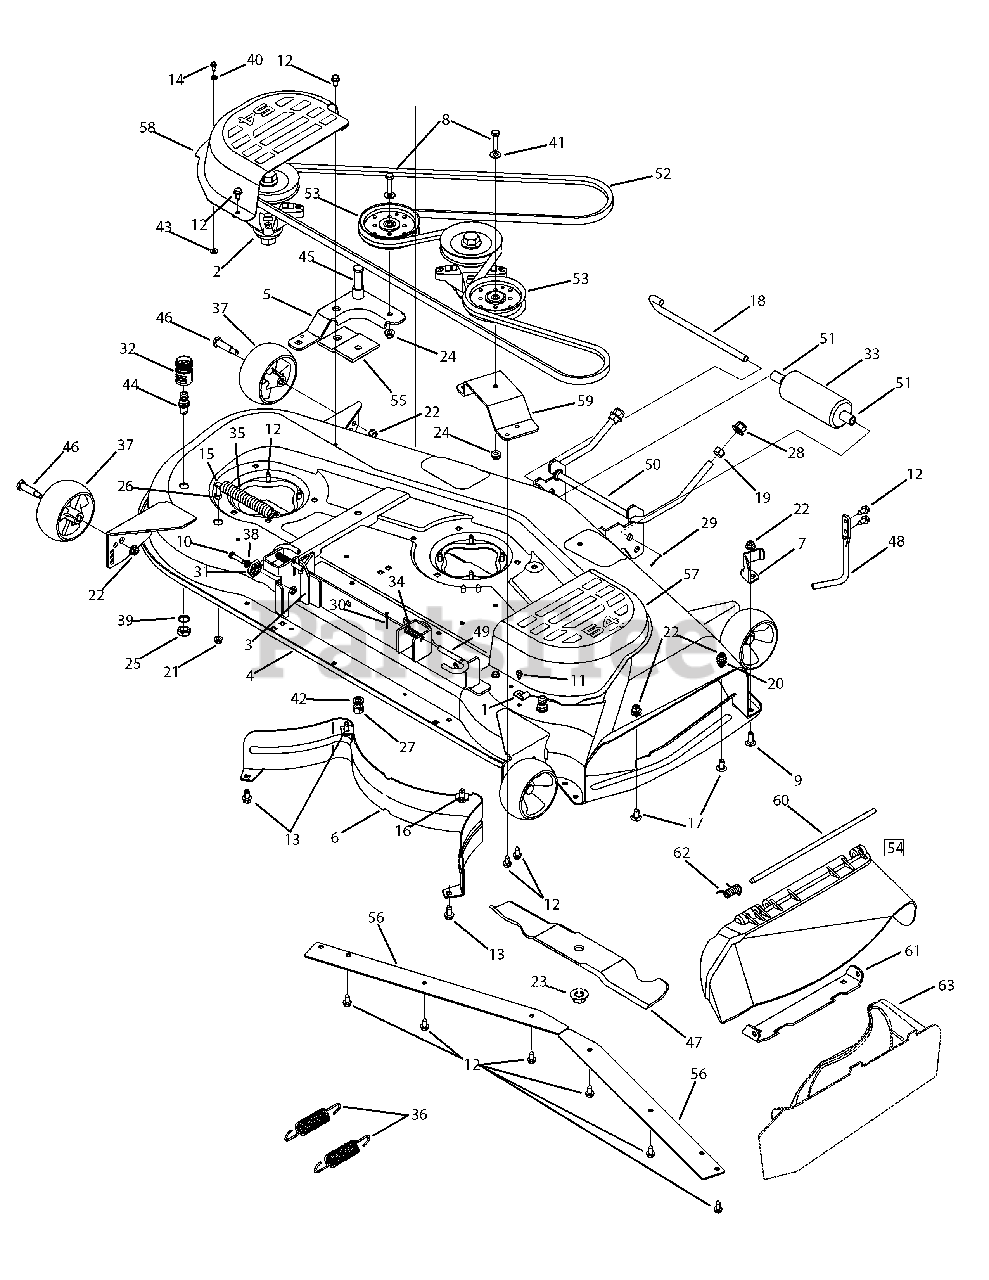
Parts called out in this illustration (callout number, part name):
1	Hook, Retainer Bracket
2	Spindle Assembly
8	Screw, 3/8-16 x 1.75
9	Screw, 3/8-16 x 1.0
10	Screw, 5/16-18 x 1.25
11	Screw, 1/4-20 x.500
12	Screw, 5/16-18 x.500
13	Screw, 3/8-16 x.750
14	Screw, 5/16-18 x.875
15	Screw, 5/16-18 x 2.00
16	Bolt, Carriage, 3/8-16 x 1.00
17	Bolt, Carriage, 3/8-16 x.750
18	Pin, Roller,.5" Dia. x 10.06
19	Nut, Hex, 1/2-13
20	Push Nut, 3/8
21	Nut, Flange Lock, 5/16-18
22	Nut, Flange Lock, 3/8-16
23	Nut, Flange, 5/8-18
24	Nut, Flange Lock, 3/8-16
25	Nut, Hex, M16-1.5
26	Nut, Hex, 5/16-18
27	Nut, Hex Lock, 1/2-13
28	Nut, Hex Lock, 1/2-13
29	Pin, Cotter, 3/32 x 1.00
30	Pin, Cotter, 1/8 x 1.25
31	Deck Adjustment Gear
32	Hose Coupler
33	Front Roller
34	Spring,.531OD x 1.75
35	Spring, Ext.,.850 Dia. x 6.415
36	Spring, Lift Assist
38	Washer, Lock, 5/16
39	Washer, Lock 5/8 Int. Tooth
40	Washer, Flat,.344 x.688 x.065
41	Washer, Flat,.406 x.875 x.059
42	Washer, Lock, 1/2
43	Washer, Flat, .407 x .812 x .135
45	Screw,.625 x 2.50 x 1/2-13
46	Bolt, Shoulder, 3/8-16; 4.96 x 2.50
47	Blade, 18.5"
49	Rod, Deck Release Handle
50	Adjustable Front Deck Rod
51	Spacer,.550 ID x.755 OD x 1.1
52	V-Belt
53	Pulley, Idler, 4.25" Dia.
54	Chute Ass’y, Side Discharge
61	Chute Mounting Bracket
62	Torsion Spring
